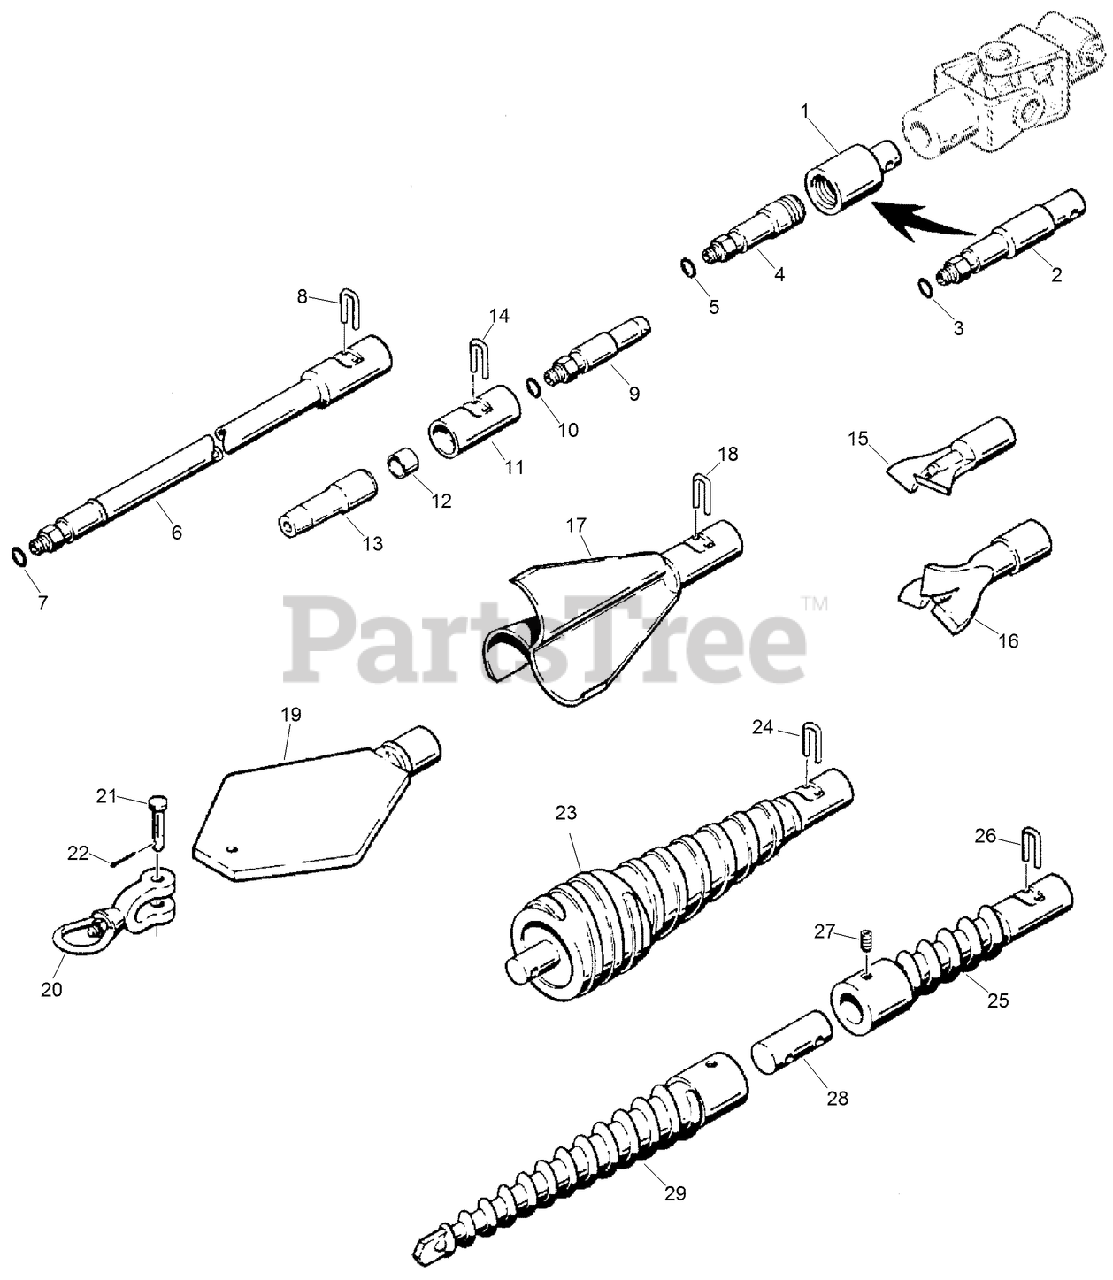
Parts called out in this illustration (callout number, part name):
1	ADAPTER - Dry Boring
2	ADAPTER-Quick Lock Male
4	ADAPTER
6	STEM-Drill, Quick Lock, 5 ft Drill
6	STEM-Drill, Quick Lock, 10 ft Drill
8	CLIP-Retainer
9	COUPLING - Quick Lock, Male
11	COUPLING
12	Bushing
13	Shaft
14	CLIP-Retainer
15	BIT-Drill, Two Blade, 2 in Blade Dia x 1 in Female PT
15	BIT-Drill, Two Blace, 3 in Bade Dia x 1 in Female PT
16	BIT-Drill, Three Blade, 3 in Blade Dia x 1 in Female PT
17	BACKREAMER-Quick Lock Female, 8 inch
17	BACKREAMER-Quick Lock Female, 12 inch
18	CLIP-Retainer
19	REAMER-Fish Plate, 4 inch
19	REAMER-Fish Plate, 6 inch
19	REAMER-Fish Plate, 8 inch
20	SWIVEL-Reamer
21	PIN-Clevis, 3/8 x 1-3/4 inch long, Special
22	PIN-COTTER
23	REAMER-Compaction, Quick Lock Female, 3-3/4 inch
24	CLIP-Retainer
25	BIT - Compaction, Quick Lock, Female, 2 in
26	CLIP-Retainer
27	BOLT - 3/8 x 1-3/4
28	COUPLING - BiT
29	BIT - Compaction, End, 2 in
